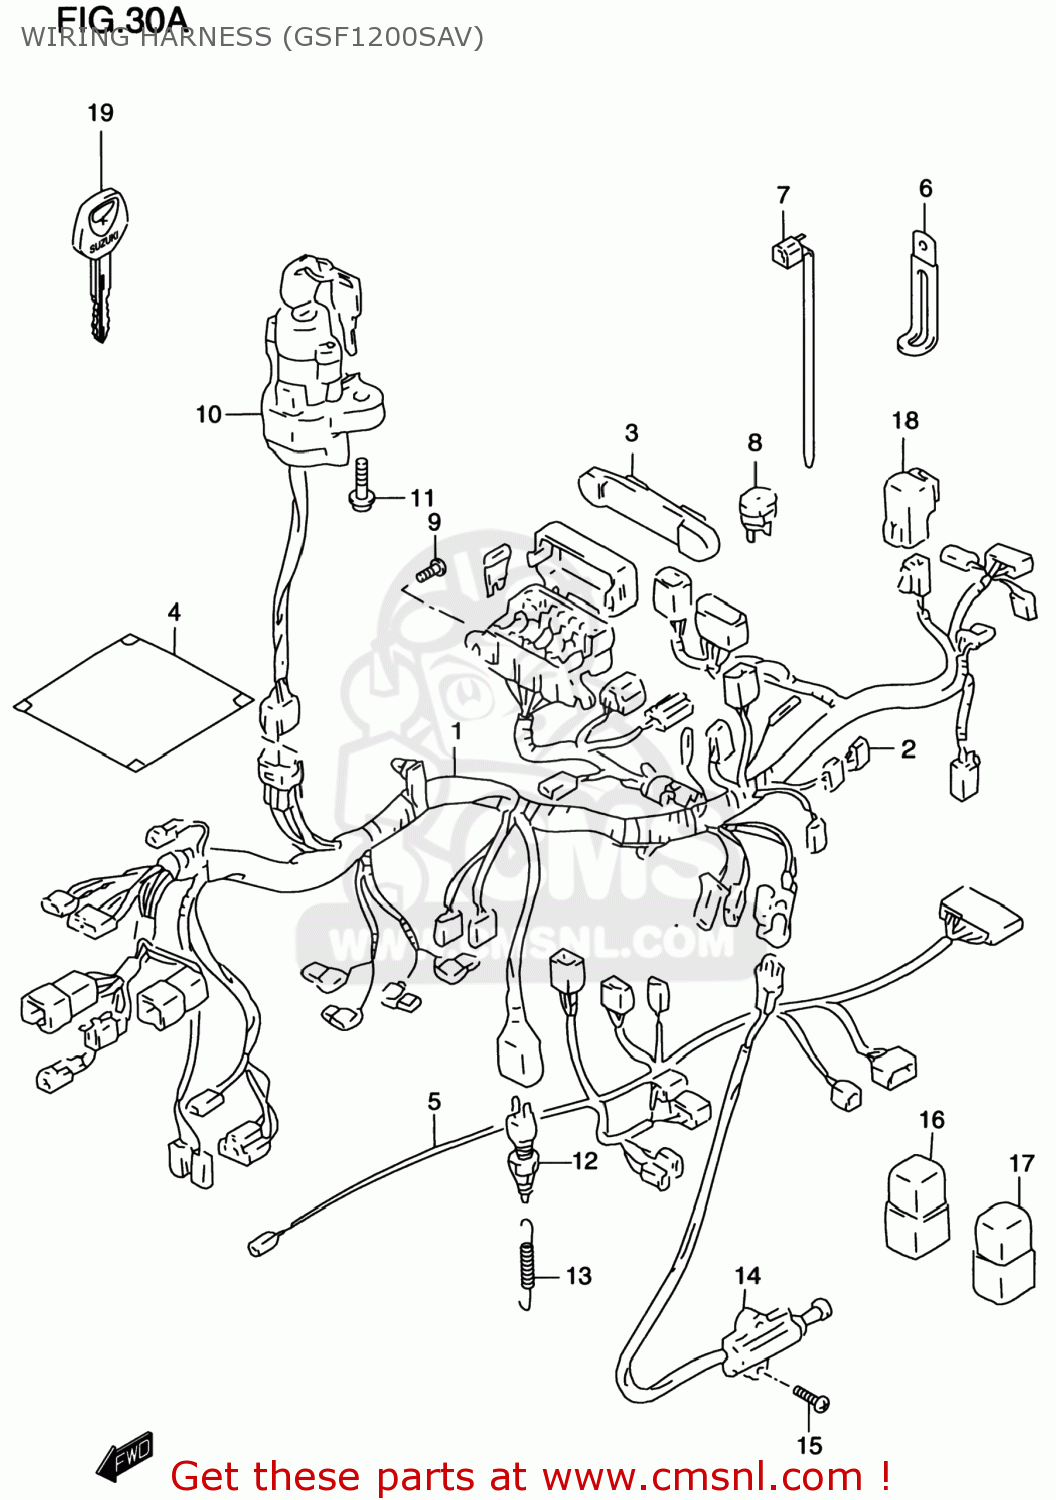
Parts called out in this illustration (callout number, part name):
1	HARNESS,WIRING NO.1
2	DIODE(STANLEY DE8804)
3	HOLDER,FUSE BOX
4	COVER,WIRING HARNESS
5	HARNESS,WIRING NO.2
6	CLAMP L:62
7	CLAMP(L:95)
8	BREAKER ASSY,CIRCUT
9	SCREW 6X12
10	LOCK ASSY,STEERING
11	BOLT(8X20)
12	SWITCH ASSY,STOP LAMP
13	SPRING
14	SWITCH ASSY,SIDE STAND
15	SCREW
16	RELAY ASSY,ABS MOTOR
17	RELAY ASSY,ABS VALVE
18	RELAY ASSY
19	KEY,BLANK
